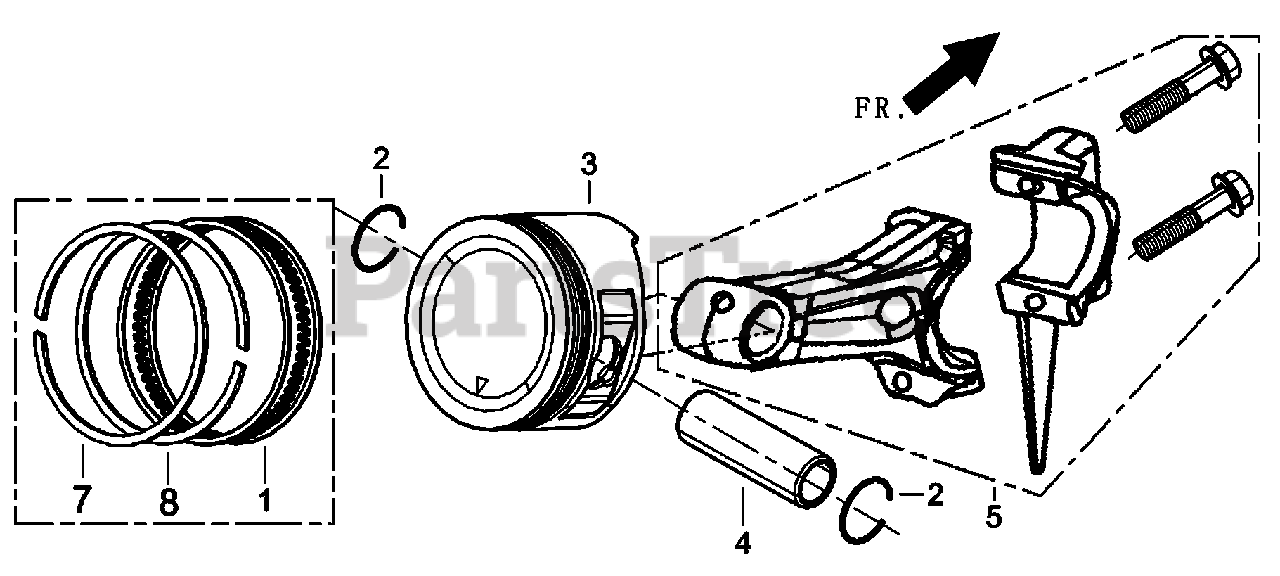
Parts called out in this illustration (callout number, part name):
1	RING SET, OIL
2	CLIP, PISTON PIN
4	PIN, PISTON
5	ROD, CONNECTING
7	RING, THE FIRST
8	RING, THE SECOND
